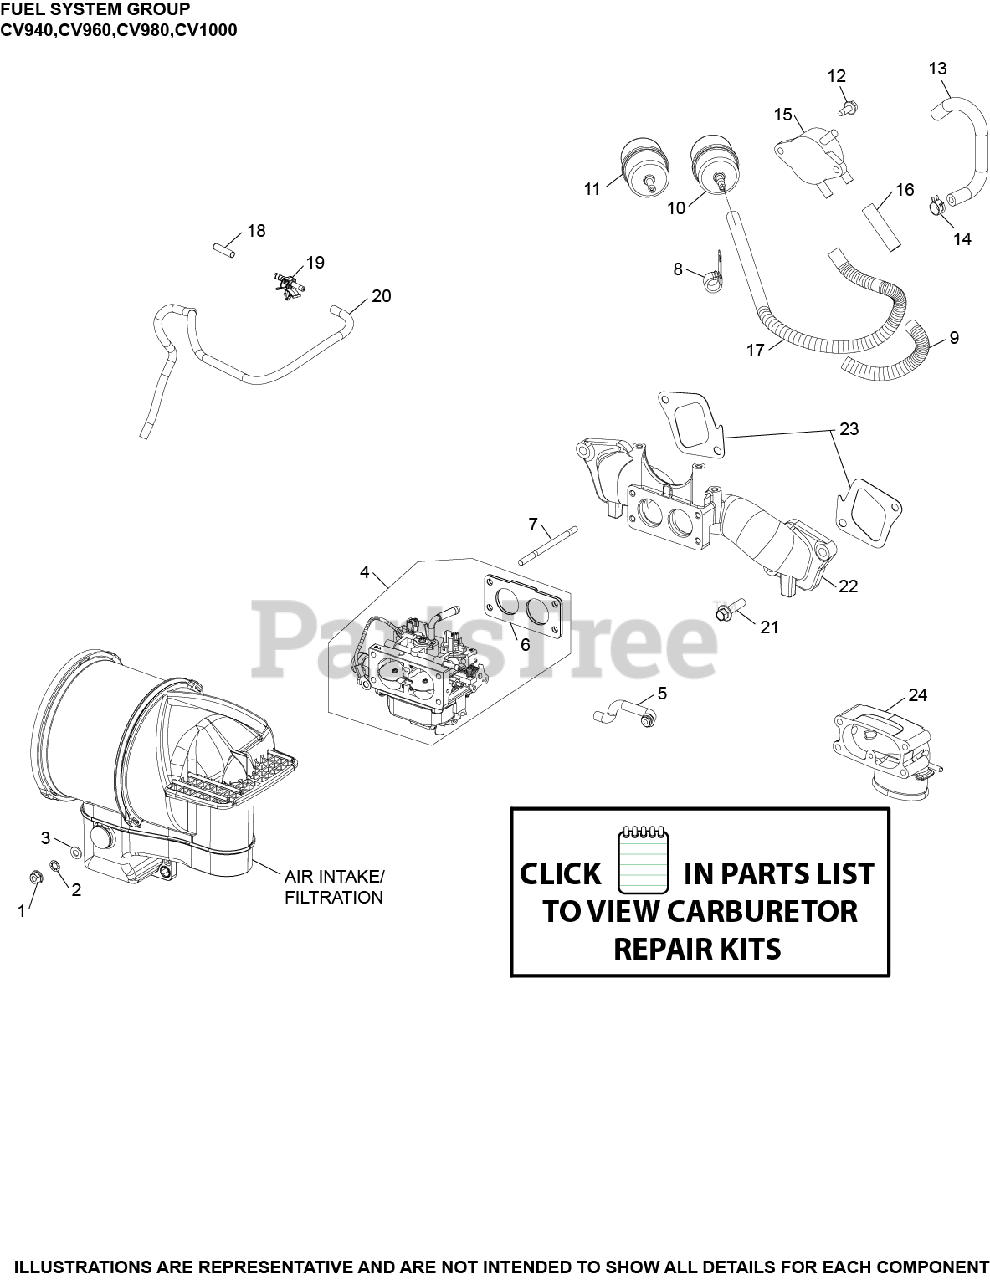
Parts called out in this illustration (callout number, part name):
1	NUT, FLG M6X1.0
3	WASHER, FLAT 1/4" (O.D. 1/2")
4	KIT, CARBURETOR
5	HOSE, CARBURETOR VENT
6	GASKET, CARBURETOR - USE 24 041 82-S
7	STUD,M6X1.0X96
8	CLIP, CABLE
9	SLEEVE, ANTI ABRASION-USE 25 431 12-S
9	SLEEVE, ANTI-ABRASION
11	FILTER, FUEL
12	SCREW,FLG THD FRM M6X1.0X16-(#25086397S)
13	HOSE, FUEL-LOW PERMEATION
14	CLAMP, HOSE (KM)-USE 25 237 31-S
15	PUMP, FUEL
16	LINE, FUEL 2" PUMP-FILTER
17	HOSE,LW PERM.FUEL 24.00"-USE 25 111 81-S
18	CAP, MASKING
19	CONNECTOR, EVAPORATIVE
20	HOSE, EVAPORATIVE
21	SCREW, FLG M8X1.25X30
22	KIT, INTAKE MANIFOLD
23	GASKET, INTAKE MANIFOLD
24	KIT, ELBOW
